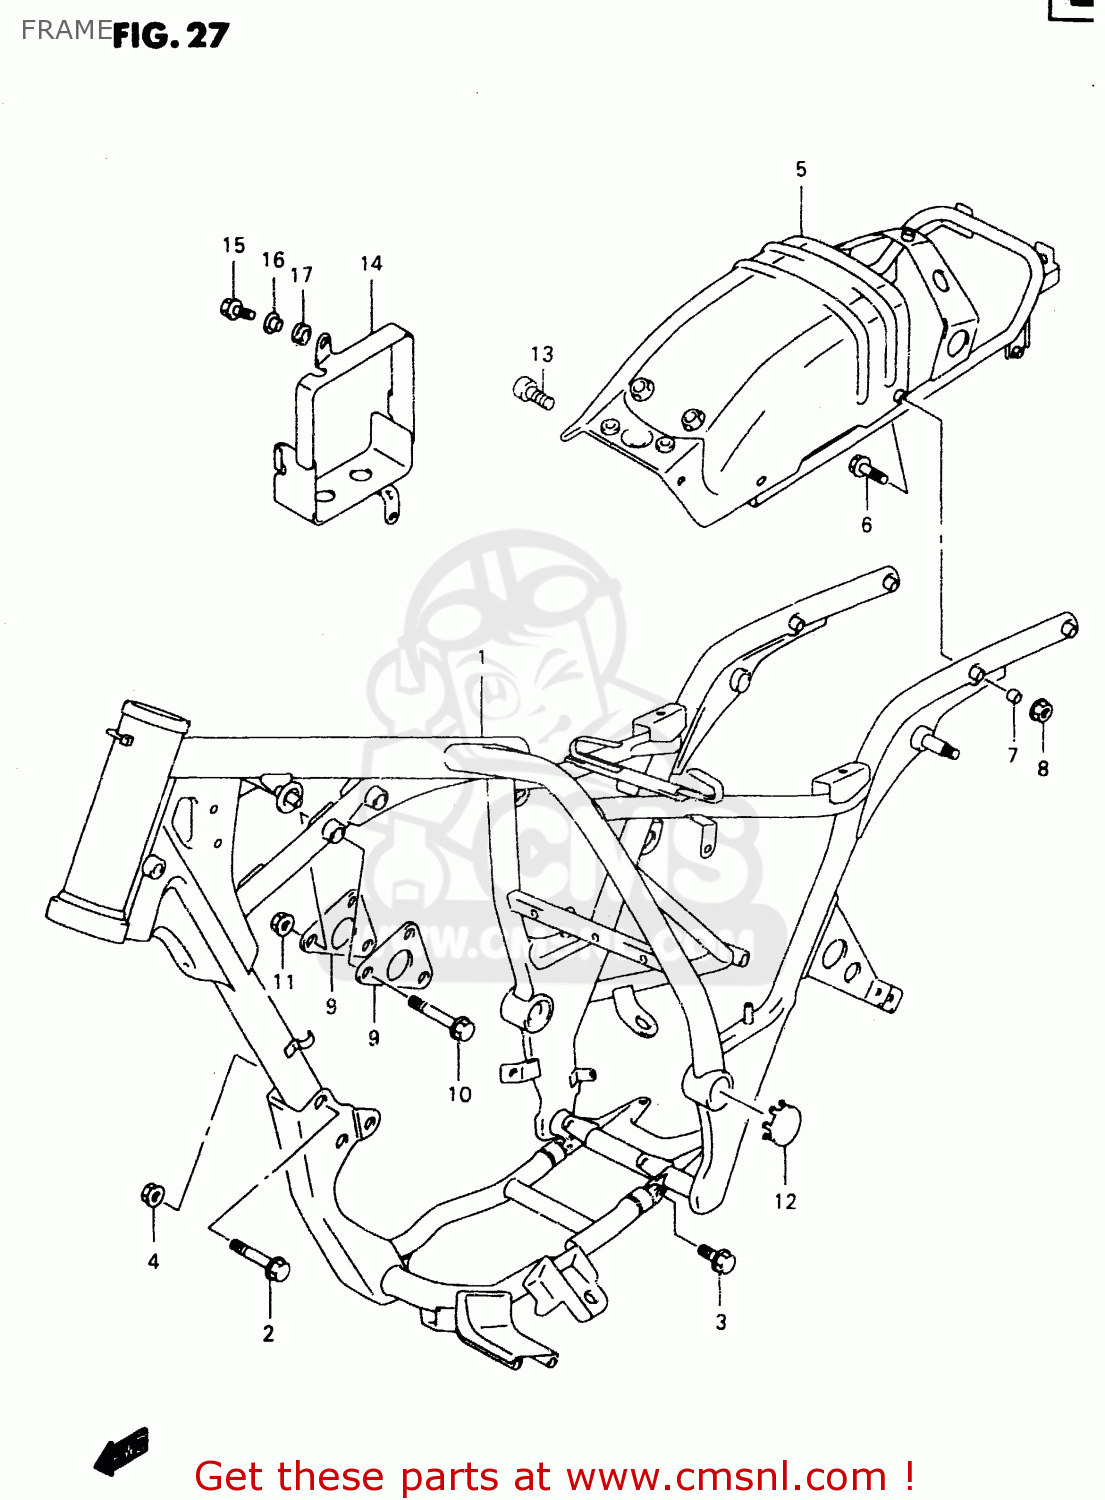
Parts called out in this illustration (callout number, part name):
1	FRAME(BLACK)
2	BOLT
3	BOLT
4	NUT
5	BRACE,RR FRAME
6	BOLT
7	SPACER(8.5X16X10)
8	NUT
9	PLATE,ENG MTG UPR
10	BOLT(8X50)
11	NUT
12	CAP,RR SWINGING ARM PIVOT,R
13	BOLT(6X12)
14	HOLDER,BATTERY
15	BOLT
16	WASHER
17	CUSHION
